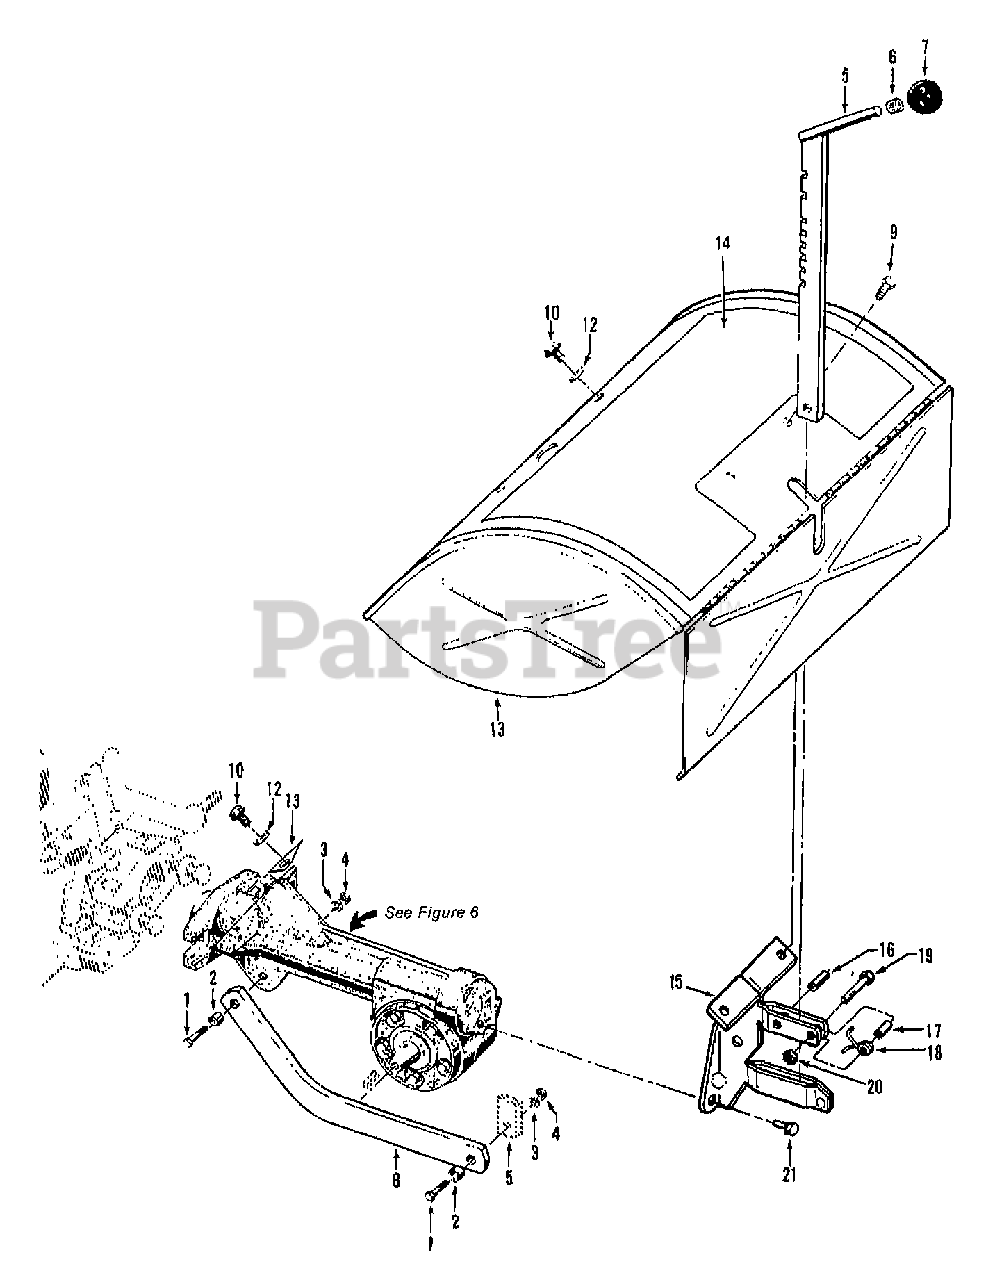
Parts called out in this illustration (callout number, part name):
1	SCR-HH 3/8-16X1.25
2	BUSHING-.5X.375X.3
3	WASHER-LK .375 @ DEPL
4	NUT-HEX 3/8-16 ZP
5	DEPTH REGULATOR W/KNOB
6	RING-TOLERANCE .5325 ID
7	KNOB-CONTROL DEPTH REGULATOR INCLUDES #9120 RETAINING RING(REF.#6)
8	BAR-DRAG RED
9	SCR-HWH 1/4-20 X .5 STH (LOCKWASHER AND NUT NOT REQUIRED)
10	SCR-HFLK 5/16-18X.62 G5ZP
10	SCR-HFLK 5/16-18X.75 ZP
11	THIS REF. NOT USED
12	WASHER-#1.125X.344 ZP
13	HOOD W/DECALS OPC SERVICE (REF.#14)
14	DECAL-HOOD INST
15	BRKT W/ROLL PIN (9308) (REF.#16)
16	PIN-ROLL .25 X 1
17	SPACER-.250X.343X.375
18	SPRING-TORSION
19	SCR-HH 1/4-20X1.0
20	NUT-LK 1/4-20
21	SCR-HFLK 5/16-18X.62 G5ZP
